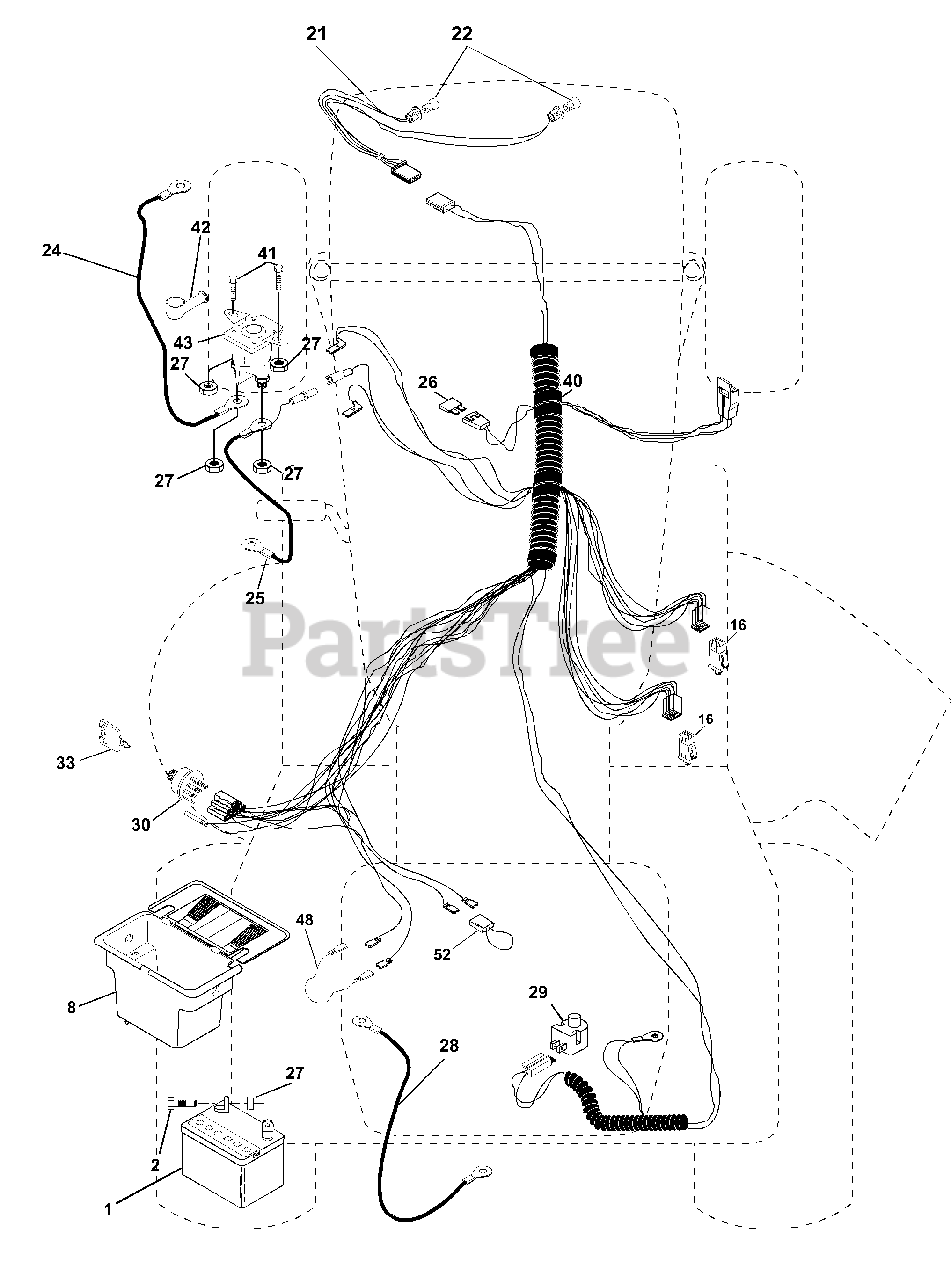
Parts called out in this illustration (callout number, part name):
1	Battery 12 Volt 25 AMP
2	Bolt Hex Hd 1/4-20unc X 3/4
8	Case Battery Mech Hinge
16	Switch Interlock Push-In
21	Harness Asm Light W/4152j
22	Bulb Light #1156
24	Cable Battery 6 Ga 11" red
25	Cable Battery 6 Ga 44" red w/16 wire
27	Nut Keps Hex 1/4-20 Unc
28	Cable Ground 6 Ga 12" black
29	Switch Plunger Nc Gray
30	Switch Ign Delta
33	Key Ign Molded Generic
40	Harness Ign.
41	Bolt Blk Fin Hex 1/4 - 20 x 1/2
42	Cover Terminal Red
43	Solenoid
48	Adapter Ammeter Rectangular
52	Protection Wire Loop
